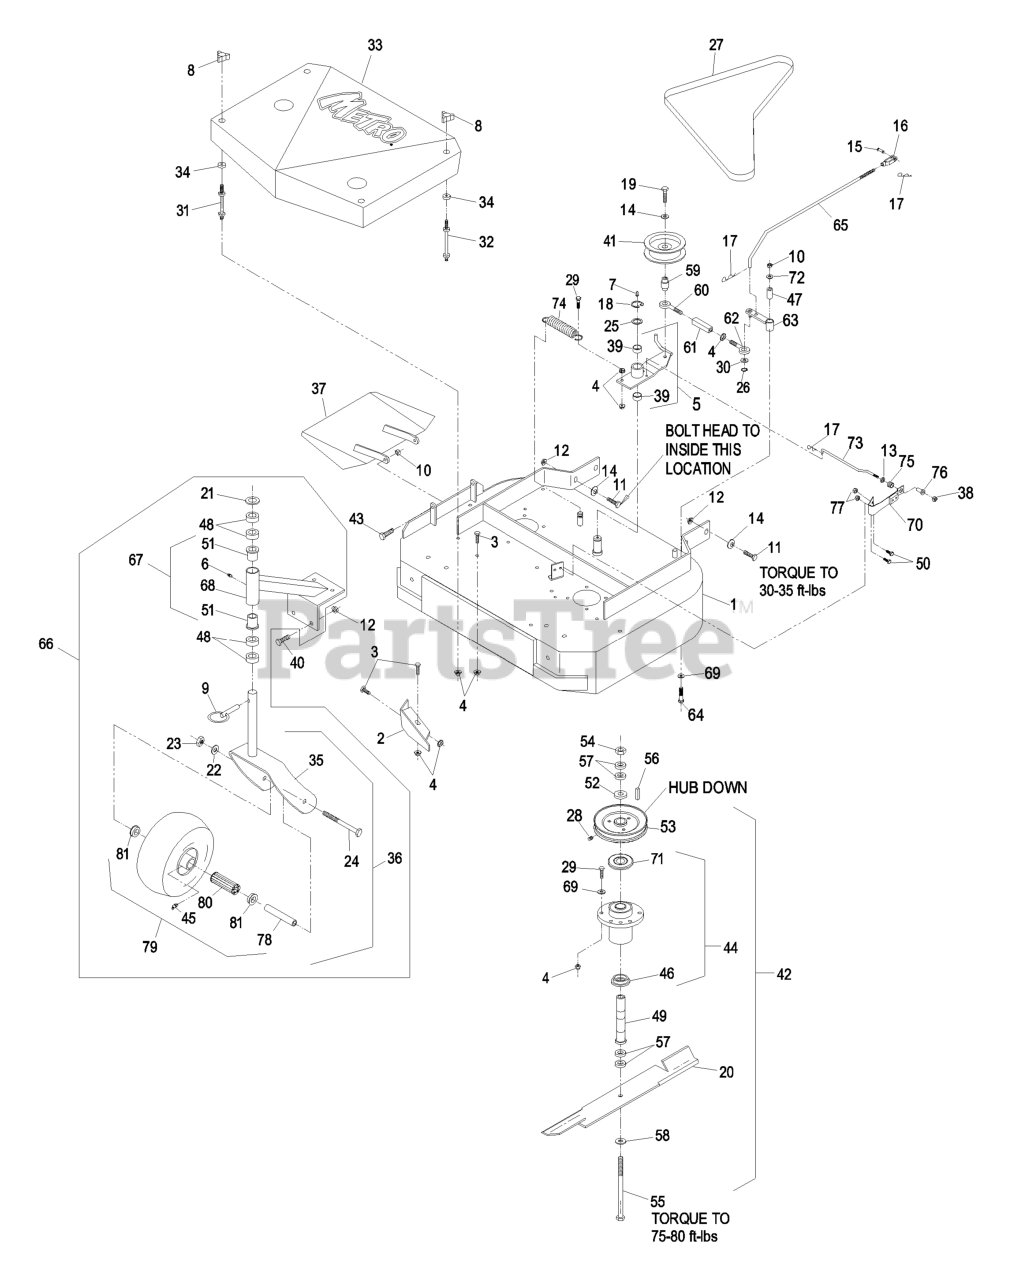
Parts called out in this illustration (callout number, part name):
1	ASM,DECK 36 RIGID
2	BAFFLE-DOGLEG
3	SCREW-HH
5	IDLER ARM ASM
6	FITTING-GREASE
7	FITTING-GREASE
8	KNOB-3 PRONG
10	NUT-LOCK, NI
11	SCREW-HH
12	NUT-HHF, WHIZ
13	RING-PUSH ON
14	WASHER-BELLEVILLE
15	PIN-CLEVIS
16	YOKE-ADJUSTABLE
17	PIN-COTTER
18	RING-RETAINING, EXT
19	SCREW-HH
21	WASHER-FLAT
22	WASHER-LOCK
23	NUT-HH
24	SCREW-HH
25	WASHER-SPINDLE
26	RING-RETAINING, EXT
27	BELT,BLADE METRO 36
28	SCREW-SET
29	SCREW-HH
30	WASHER-PLAIN
31	STUD-SHIELD, BELT (SHORT)
32	STUD-SHIELD, BELT (LONG)
36	ASM,CASTER/WHEEL
37	WLD,CHUTE 36 RIGID
38	NUT-LOCK, NI
39	SLEEVE-BEARING
40	SCREW-HH
42	ASM, CUTTER HOUSING OUTER
43	SCREW-HH
44	KIT, CUTTER HOUSING
45	FITTING-GREASE
46	SPACER-GUARD, BOTTOM
47	TUBE-PIVOT
48	SPACER-CASTER
49	TUBE-SPINDLE, SHORT
50	SCREW-HH
51	BEARING-FLANGED
52	WASHER-RETAINER, SHEAVE
53	SHEAVE
54	NUT-HEX
55	SCREW-CAP, HH
58	WASHER-SPRING
59	BUSHING-ENGAGEMENT
60	EYEBOLT-THREAD, LH
61	BODY-TURNBUCKLE
62	EYEBOLT-THREAD, RH
63	ARM-ASSIST, 32/36
64	SCREW-HH
65	ARM-ASSIST, LINKAGE
66	ASM,CASTER/MOUNT
67	SUPPORT ASM
69	WASHER-SPRING
70	PAD AND SPRING ASM
71	GUARD-BEARING, TOP
72	WASHER-FLAT
73	ROD-BRAKE
74	SPRING-EXTENSION
75	SPRING-COMPRESSION
76	SPACER-FLANGED
77	NUT-LOCK, NI
79	KIT, SP CASTER WHEEL REPL
80	BEARING
81	BUSHING
